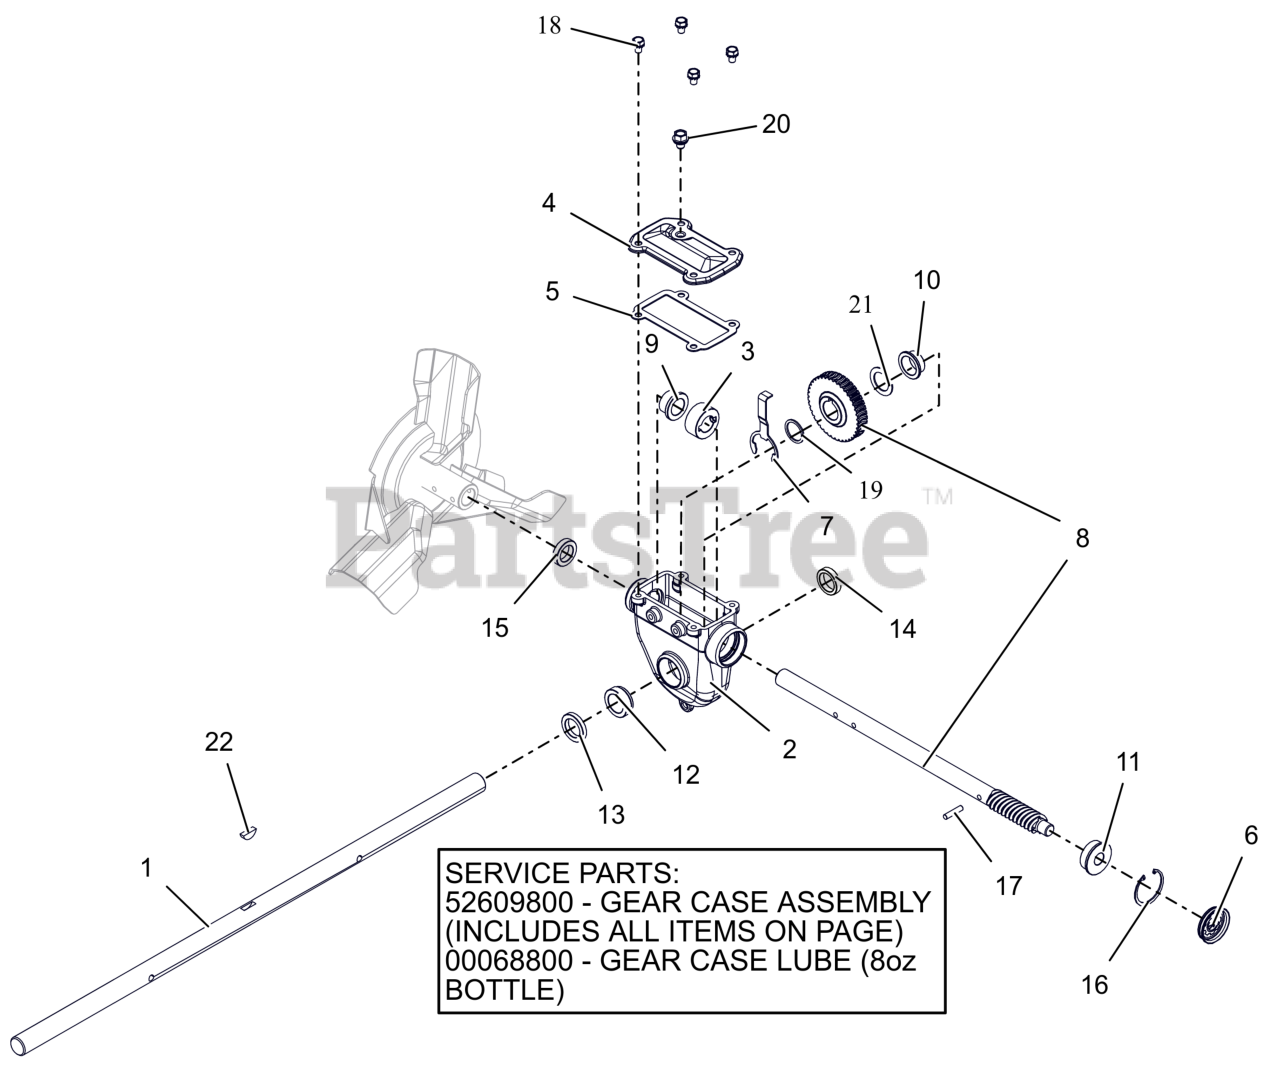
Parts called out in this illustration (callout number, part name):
1	SHAFT, RAKE-32"
2	GEARCASE, LARGE MACHINED
2	GEAR CASE, 32" IRON PRO TOP-LD
2	ARIENS L3 LUBE, 8 OZ BOTTLE
3	THRUST COLLAR, .875"ID SLIPFIT
4	COVER, TOP - LARGE IRON
5	GASKET, TOP - LARGE GEARCASE
6	COVER, GEAR CASE 1.75"
7	BUSHING RETAINER, LARGE
8	ASSY, WORM SHAFT & GEAR
9	BSHG-FLG .879X1.128X.75X1.45
10	BSHG-FLG 1.006X1.128X.555X1.45
11	BSHG-FLG .628X1.503X.58X1.725
12	BSHG-FLG LARGE, RIGHT
13	SEAL-OIL .999X1.500X.250 TBC29
14	SEAL-OIL .999X1.375X.312 TBC29
15	SEAL-OIL .873X1.375X.312 TBC29
16	RG-RTNG-INT 1.750X.062
17	PIN-STR .250X1.12 6150
18	BLT, SEMS .31-18X.50 G5 ZCC
19	WSHR, FLT 1.010X1.250X.068 ZCC
20	SCR, .380-15X.500 W/SEAL WASHER
21	WSHR, FLT 1.010X1.505X.062 ZCC
22	KEY-WDRF .25X.875 HRD #A
